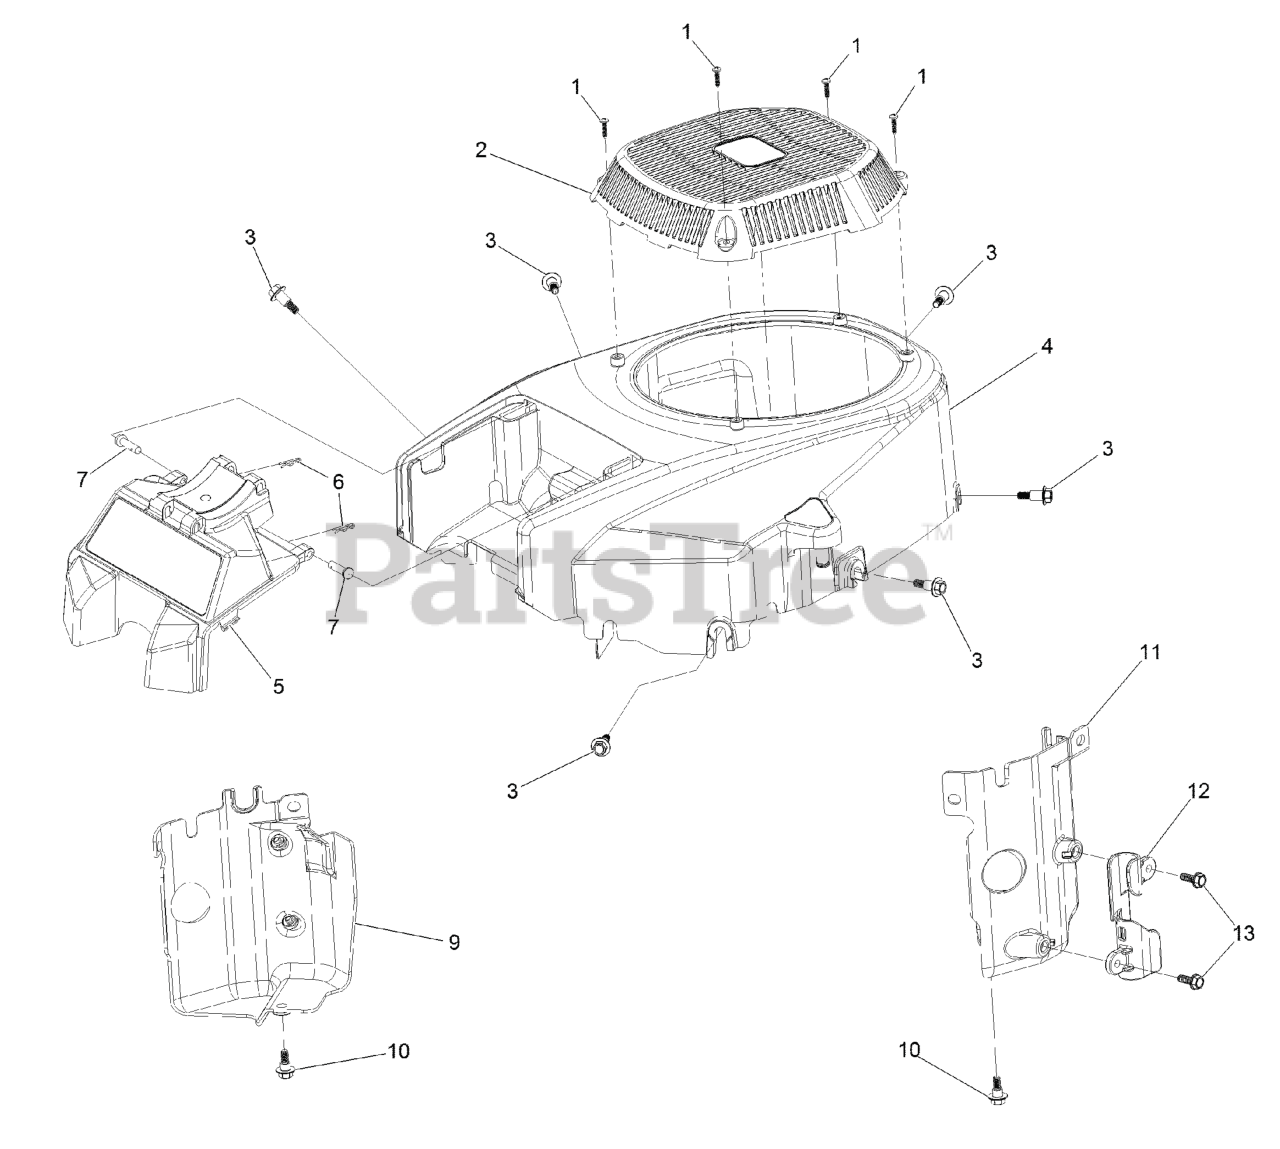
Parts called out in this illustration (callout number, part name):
1	SCREW-PPH, PLASTIC
2	COVER-FAN
3	SCREW-SHOULDER, HWH
4	SHROUD-ENGINE
5	SUPPORT-FILTER
6	PIN-HAIR
9	BAFFLE-AIR, LEFT
10	SCREW-SHOULDER, HHF
11	BAFFLE-AIR, RIGHT
12	CLEAT-HOSE
13	SCREW-HHF
